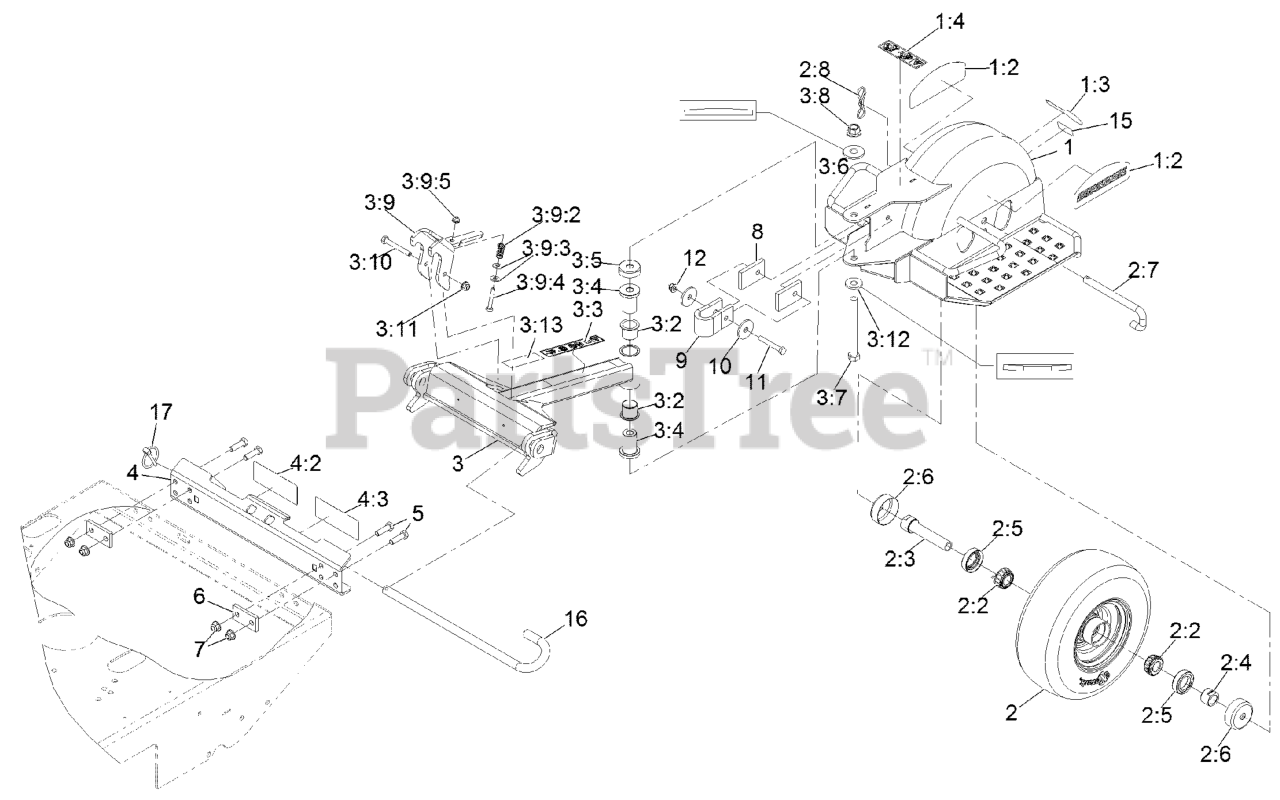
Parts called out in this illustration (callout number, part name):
1	ASM-SULKY FRAME W/ DECALS
1:2	DECAL, STANDON
1:3	DECAL, EXMARK
1:4	DECAL-WARNING HAND PINCH
2	ASM, WHEEL AND BEARINGS
2:2	BEARING-CONE, TAPERED ROLLER
2:3	CASTER AXLE ASM
2:4	SPACER-NUT
2:5	SEAL-CASTER
2:6	GUARD-SEAL
2:7	PIN, CASTER
2:8	PIN-COTTER, LOCKING
3	ASM, DRAW BAR
3:2	BUSHING-PIVOT
3:3	DECAL-SULKY HAZARD
3:4	SPACER, PIVOT
3:5	COVER, DUST
3:6	WASHER-BELLEVILLE
3:7	SCREW-HH
3:8	Nut-Lock 1/2-13
3:9	TRANSPORT LATCH ASM
3:9:2	SPRING, COMPRESSION
3:9:3	WASHER-FLAT
3:9:4	SCREW-HH
3:10	SCREW-HH
3:11	NUT-HF, NI
3:12	WASHER-SPRING
3:13	DECAL-WARNING
4	ASM, MOUNT PLATE
4:2	DECAL-BELT DRIVE WARNING
4:3	DECAL-WARNING, SULKY
5	SCREW-HH
6	PLATE,BACK-UP (PLATED)
7	NUT-HF, NI
8	PAD,STOP
9	STOP, ROTATION
11	SCREW-HH
12	NUT-HF, NI
15	Decal-Patent
16	PIN, PIVOT
17	PIN-LYNCH
